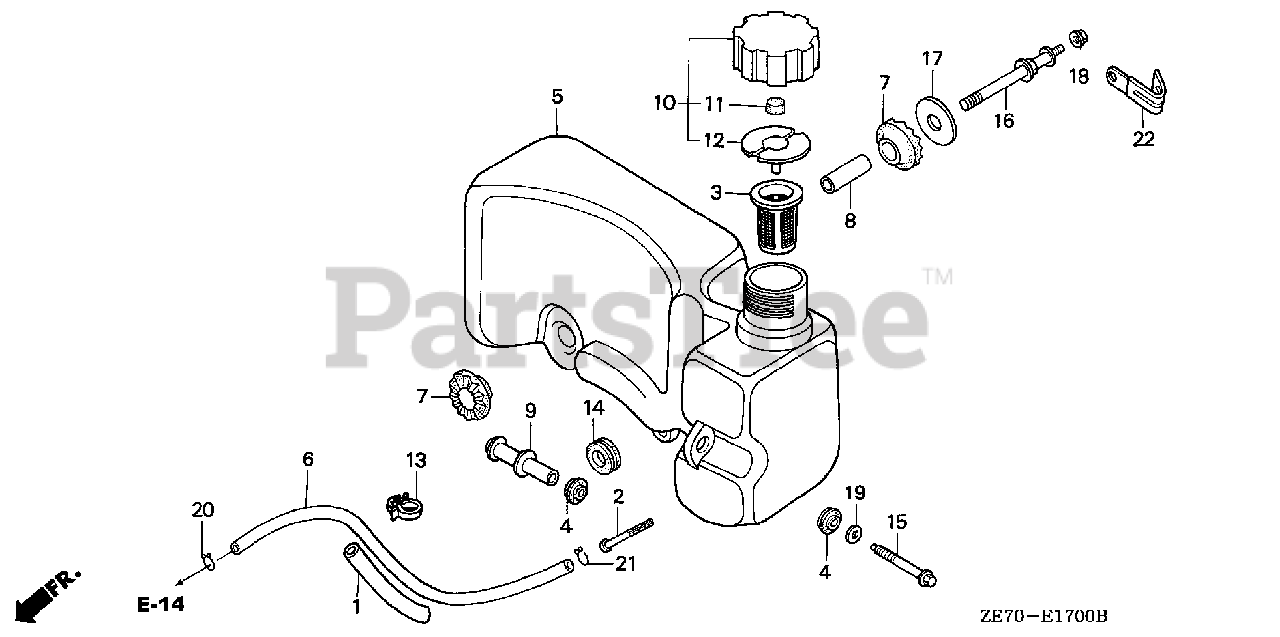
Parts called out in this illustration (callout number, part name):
1	RUBBER, SUPPORTER (107MM)
2	FILTER, FUEL
4	RUBBER, TANK SETTING
5	TANK, FUEL
6	TUBE, FUEL
7	RUBBER B, TANK MOUNTING
8	COLLAR, TANK SETTING
9	COLLAR, TANK
10	CAP ASSY., FUEL TANK
11	SPONGE, FUEL CAP BREATHER
12	GASKET, FUEL CAP
13	CLIP, IGNITION WIRE (8MM)
14	CUSHION, RR. FENDER
15	BOLT, FLANGE (6X50)
16	BOLT, TANK STAY
17	WASHER, TANK MOUNTING
18	NUT, FLANGE (6MM)
19	WASHER, PLAIN (6MM)
20	CLIP, TUBE (B8)
21	CLIP, TUBE (C11)
